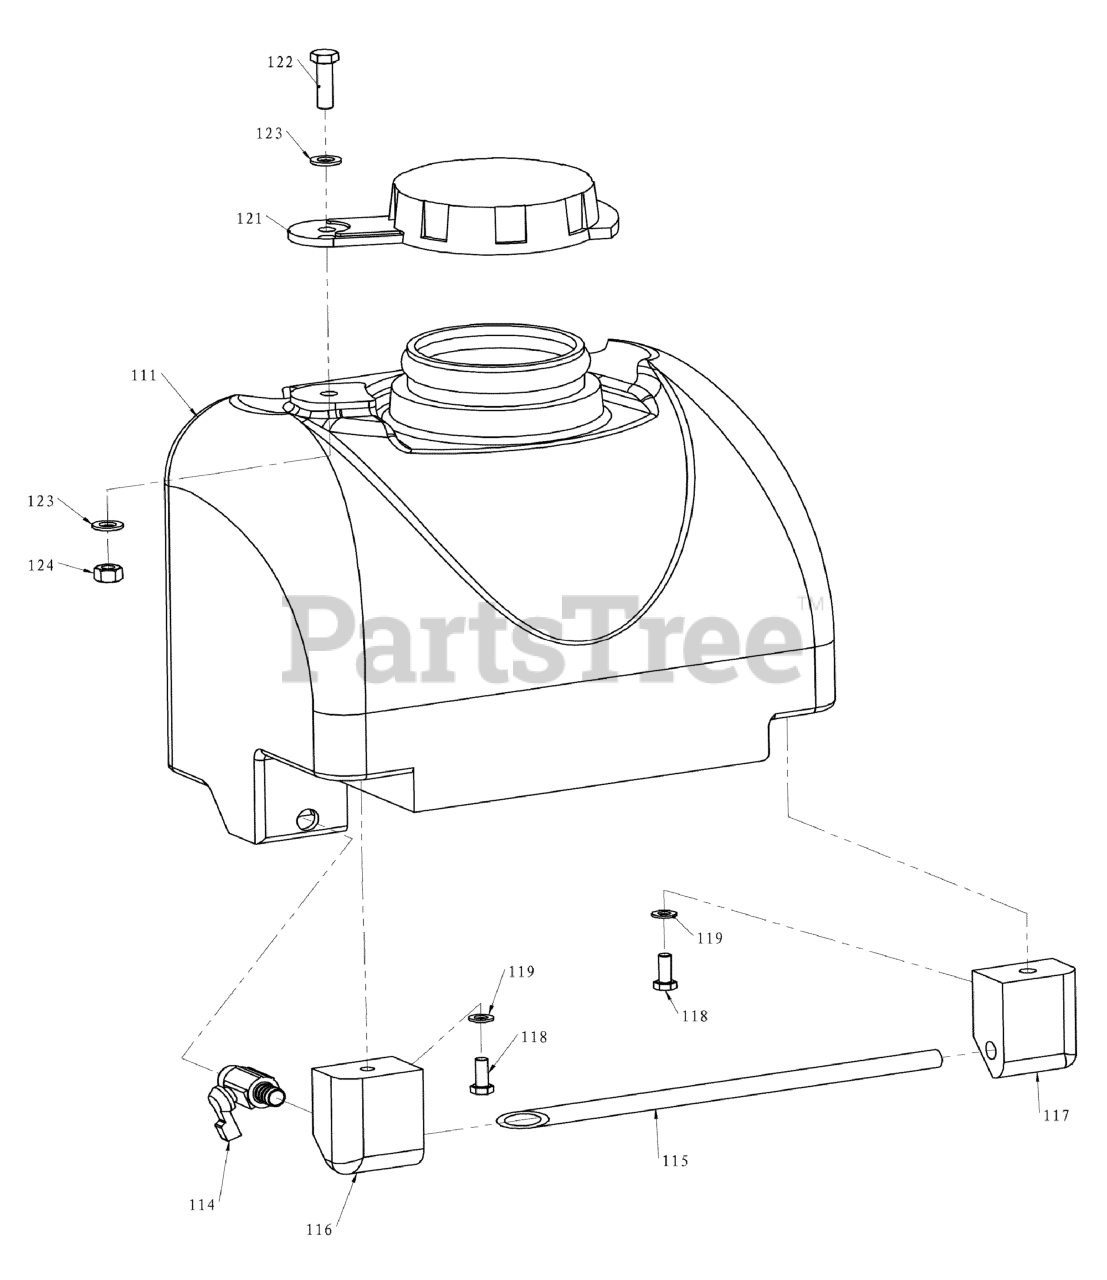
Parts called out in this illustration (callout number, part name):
111	WATER TANK
115	SPRINKLING PIPE
116	PIPE HOLDER, LH
117	PIPE HOLDER, RH
118	BOLT, M8 × 30, GB5783
119	WASHER, 8, GB95
121	CAP, Water Tank
122	BOLT, M10 × 30, GB5783
123	WASHER, 10, GB95
124	NUT, Nylon, M10, GB170
133	CLAMP, 12-20
